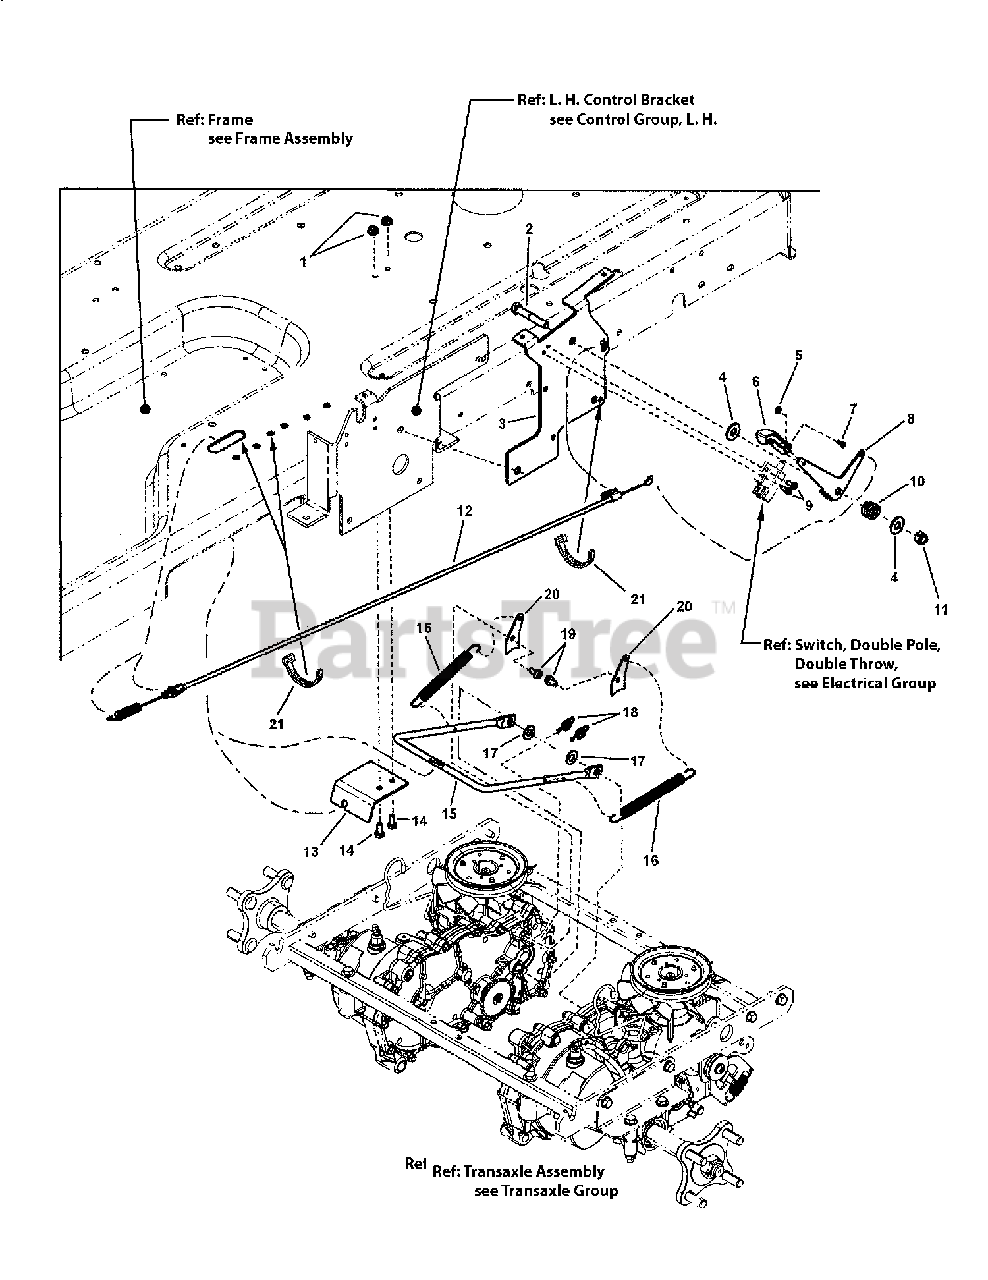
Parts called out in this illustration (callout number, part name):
1	NUT, 1/4-20 Hex Flange Lock, Black
2	SCREW, 3/8-16 x 2-1/4" Hex Head Cap, GR 5, YZ
3	BRACKET, Lever, Park Brake
4	WASHER, 7/16" Flat, YZ
5	NUT, #8-32 Hex, GR 2B, YZ
6	LEVER, Throttle Control
7	SCREW, #8-32 x 3/8" Cross Recess Filister Head, GR 2, BZ
8	LEVER, Park Brake
9	SCREW, #10-24 x 1/2" Hex Washer Self-Tap (Torx)
10	SPRING, Friction Pack
11	NUT, 3/8-16,Hex Nyloc, YZ
12	CABLE, Park Brake, RZT
13	BRACKET, Cable, Park Brake
14	SCREW, 1/4-20 x 5/8" Hex Head Cap, GR 5 YZ
15	ROD, Park Brake, RZT
16	SPRING, Extension, 0.562 OD x 4.250 LG .049 Wire, Black
17	WASHER, 3/8" Flat (SAE) YZ
18	COTTER PIN, 1/2 Self, YZ
19	SCREW, 1/4-20 x 1/2" Hex Washer Self-Tap, Black
20	TAB, Spring, Park Brake
21	CABLE TIE, 7.0
